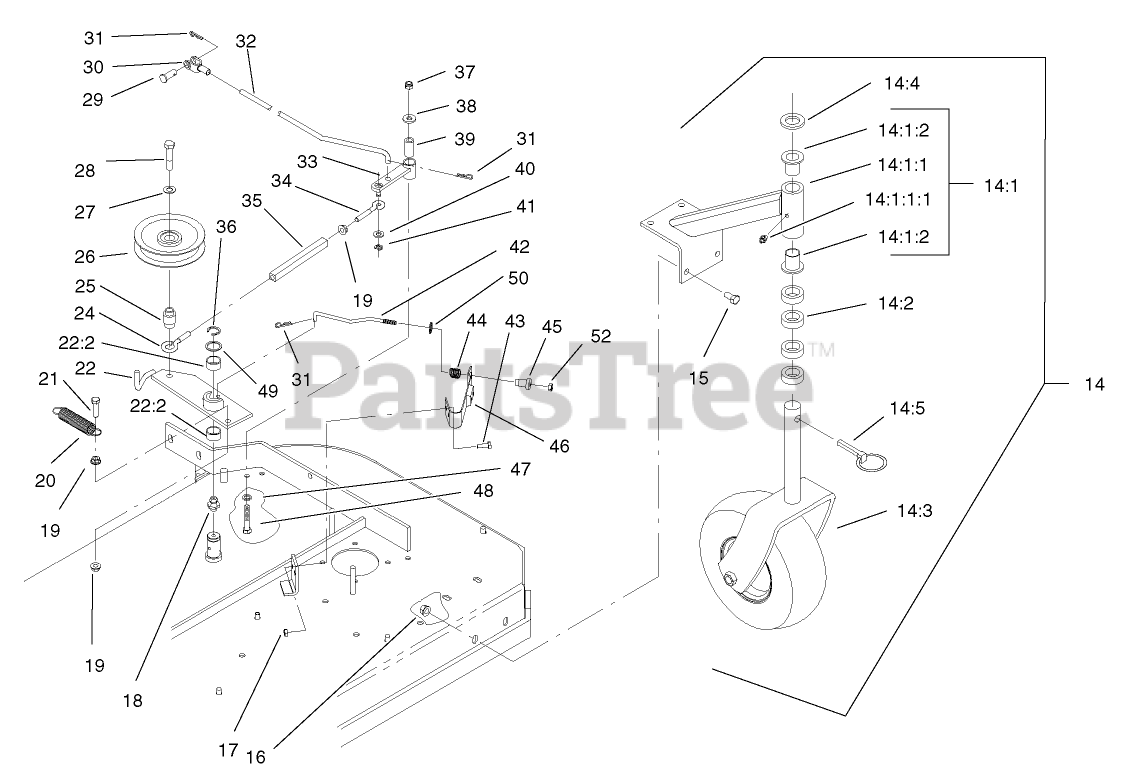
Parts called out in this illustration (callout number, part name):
14	CASTER/MOUNT ASM
14:1	Support ASM
14:1:1	SUPPORT-CASTER
14:1:1:1	FITTING-GREASE
14:1:2	BEARING-FLANGED
14:2	SPACER-CASTER
14:3	CASTER/WHEEL ASM
14:4	WASHER-FLAT
15	SCREW-HH
16	NUT-HHF, WHIZ
17	NUT-LOCK, NI
18	FITTING-GREASE
19	NUT-HF
20	SPRING-EXTENSION
21	SCREW-HH
22	ASM,IDLER ARM/BUSHINGS
22:2	SLEEVE-BEARING
24	EYEBOLT-THREAD, LH
25	BUSHING-ENGAGEMENT
26	PULLEY-IDLER
27	WASHER-BELLEVILLE
28	SCREW-HH
29	PIN-CLEVIS
30	YOKE-ADJUSTABLE
31	PIN-COTTER
32	ARM-ASSIST, LINKAGE
33	ARM-ASSIST
34	EYEBOLT-THREAD, RH
35	BODY-TURNBUCKLE
36	RING-RETAINING, EXT
37	NUT-LOCK, NI
38	WASHER-FLAT
39	TUBE-PIVOT
40	WASHER-PLAIN
41	RING-RETAINING, EXT
42	ROD-BRAKE
43	SCREW-HH
44	SPRING-COMPRESSION
45	SPACER-FLANGED
46	PAD AND SPRING ASM
47	WASHER-SPRING
48	SCREW-HH
49	WASHER-SPINDLE
50	RING-PUSH ON
52	NUT-LOCK, NI
